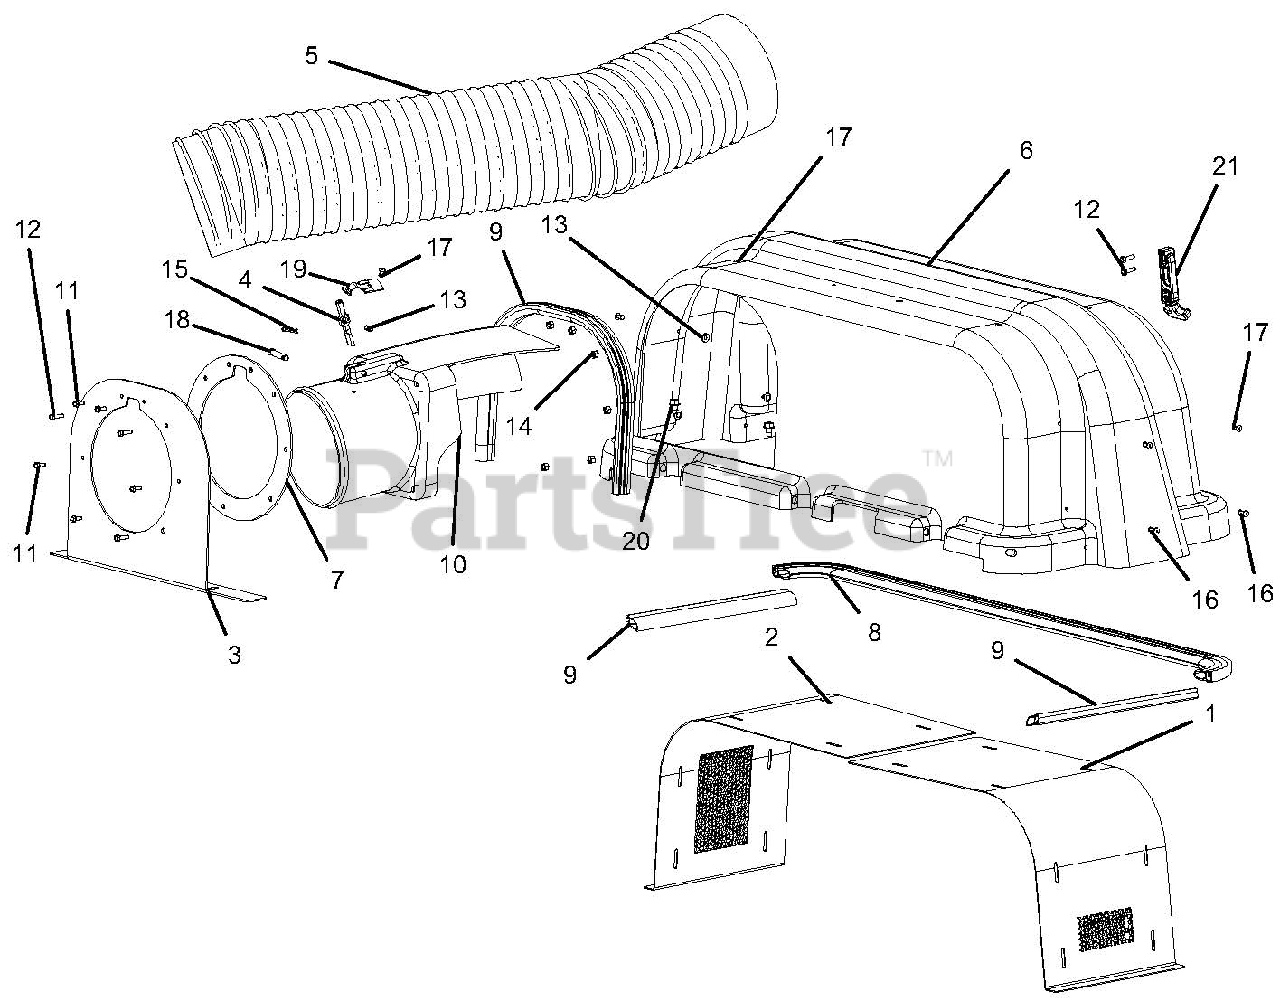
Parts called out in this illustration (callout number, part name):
1	WMT-BAGGER HOOD VENT, LH
2	WMT-BAGGER HOOD VENT, RH
3	WLDMT, TUBE SUPPORT
4	INDICATOR, FLOW
5	BAGGER HOSE, 45"
6	COVER, 2-BUCKET BAGGER
7	SEAL, UPPER BOOT
8	SEAL, BULB - BAGGER HOOD
9	SEAL, BULK
10	BOOT, UPPER
11	SCR-MCH 10-24X.50 HWH YWZC
12	SCR-MCH 10-24X.75 HWH YWZC
13	WSHR-FL-STL.219X.50X.049 YWZC
14	NUT-LK-NYL 10-24 W/INSRT YWZC
15	PIN-HAIR, ENDRIES #25 YWZC
16	.187X.6835 DOME ST
17	RVT-POP.187X.527 DOME ST
18	PIN-CLEV .309 X 1.625 YWZC
19	THUMB LATCH
20	SCR-TAP .31-18X.50 HWH TR YWZ
21	LATCH, RUBBER
